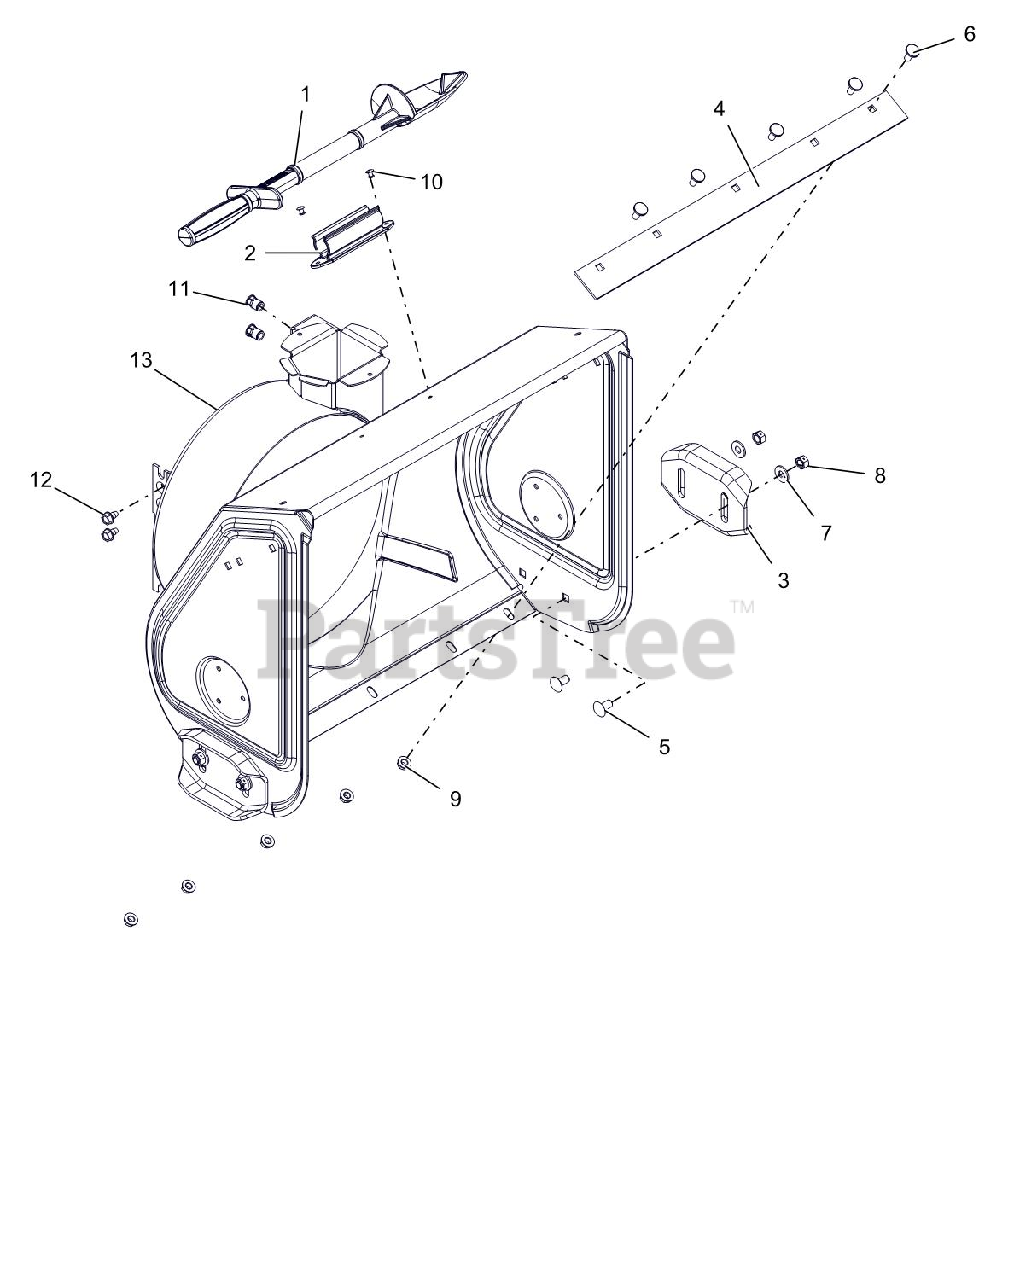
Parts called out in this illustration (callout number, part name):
1	DEVICE, SNOW CLEAN OUT
2	MOUNT, SNOW CLEAN OUT
3	SKID SHOE, REVERSIBLE - ORANGE
4	SCRAPER BLADE, 22" COMPACT
5	@BLT-RHDSSQNK .38-16X.75 G5YZ
6	BOLT, MODIFIED HEAD CARRIAGE
7	@WSHR-FL-STL.38X.875X.083 YWZC
8	@NUT-LK-CTR .38-16 YWZC
9	@NUT-LK-TOP-FLG .31-18 YWZC
10	RVT-POP .187 YZ
11	NUT, THREADED INSERT .38-16
12	@SCR-TAP .31-18X.50 HWH TR YWZ
13	BLOWER HOUSING, 22" HI ORANGE
